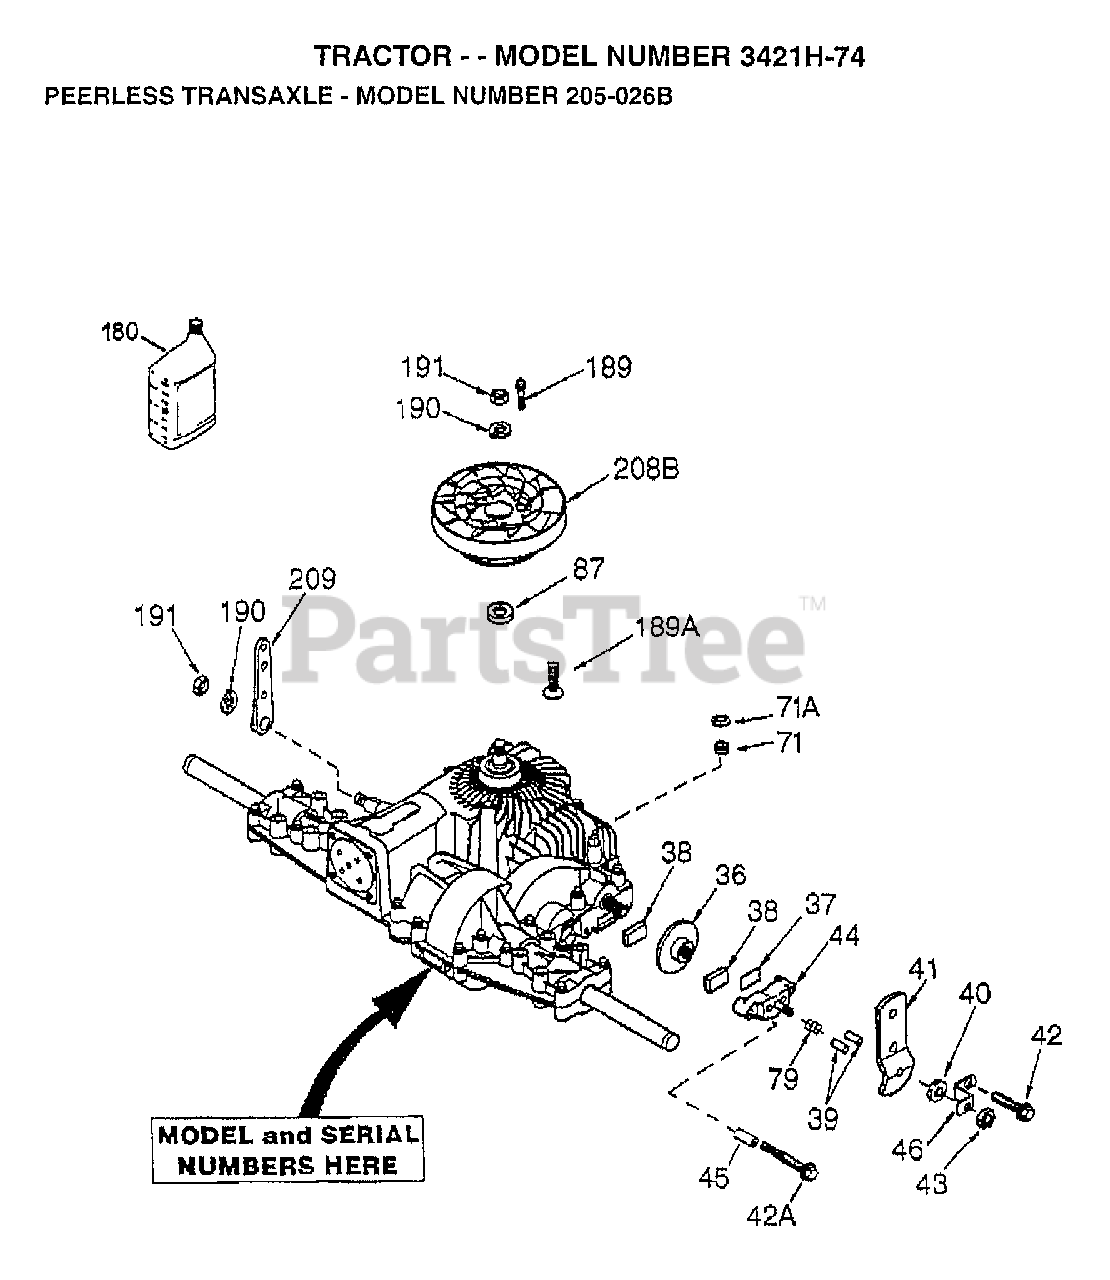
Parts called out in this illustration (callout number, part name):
37	PLATE BRAKE PAD
41	BRAKE LEVER
42	SCREW, 1/4-20 X 1-1/4
42A	SCREW, 1/4-20 X 2-1/4
43	LOCKNUT 5/16-24
44	HOLDER BRAKE PAD
46	BRAKE LEVER BRACKET
71	SEAL SQUARE CUT
180	GEAR OIL 80W90
189	DRIVE SCREW
208B	FAN/COUPLING
209	CONTROL LEVER
